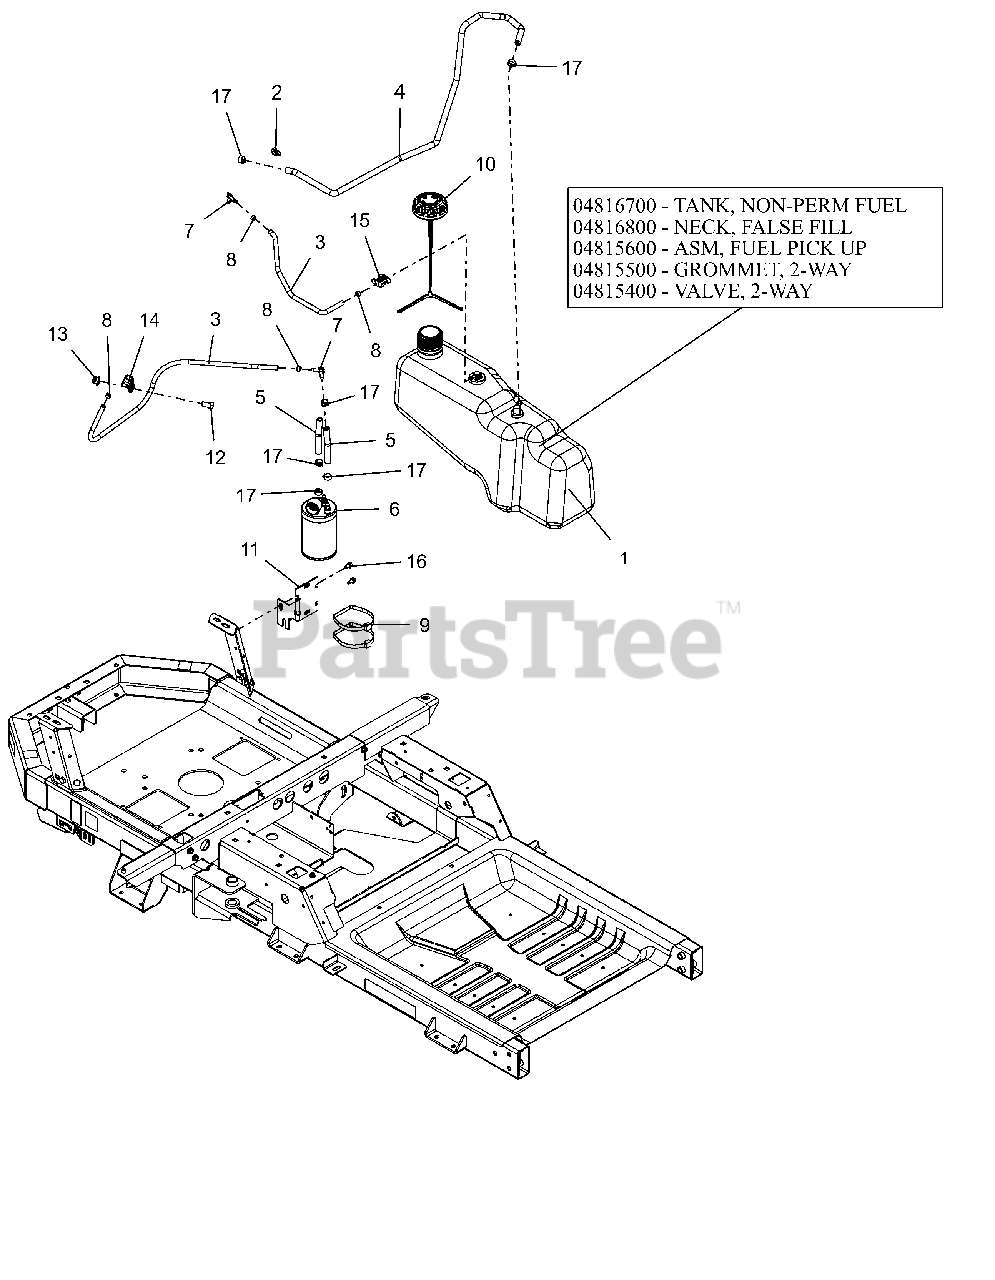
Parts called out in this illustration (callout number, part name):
1	ASM,TANK NON-PERM FUEL
1	TANK, ZOOM/ZT NON-PERM, FUEL
1	NECK, FALSE FILL ZOOM/ZT
1	ASM, FUEL PICK-UP ZOOM/ZT 2015
1	GROMMET, 2-WAY
1	VALVE, 2-WAY
2	ROUTING CLIP (1/2" ID)
3	HOSE, .188 LOW-PERM BULK GAS
4	HOSE, .25 LOW-PERM BULK GAS
5	HOSE, .25 LOW-PERM BULK GAS
6	CARBON CANISTER, 300CC
7	FITTING-3/16X1/4 90DEGREE VAC
8	CLAMP-HOSE, SPRING .188
9	P-PLASTIC TIE STRAP LARGE
10	CAP, FUEL VENT-IN 2.25" RATCH.
11	BRKT, CARB CANISTER MOUNT
12	@BLT-HEX .38-16X.75 GR5 YWZC
13	@NUT-LK-NYL-FLG .38-16 YWZC
14	CLAMP, CUSHIONED STEEL
15	CLIP, T, .38-.50
16	SCR-TAP .25-20X.50 HWH TR YWZ
17	CLAMP, FUEL LINE
